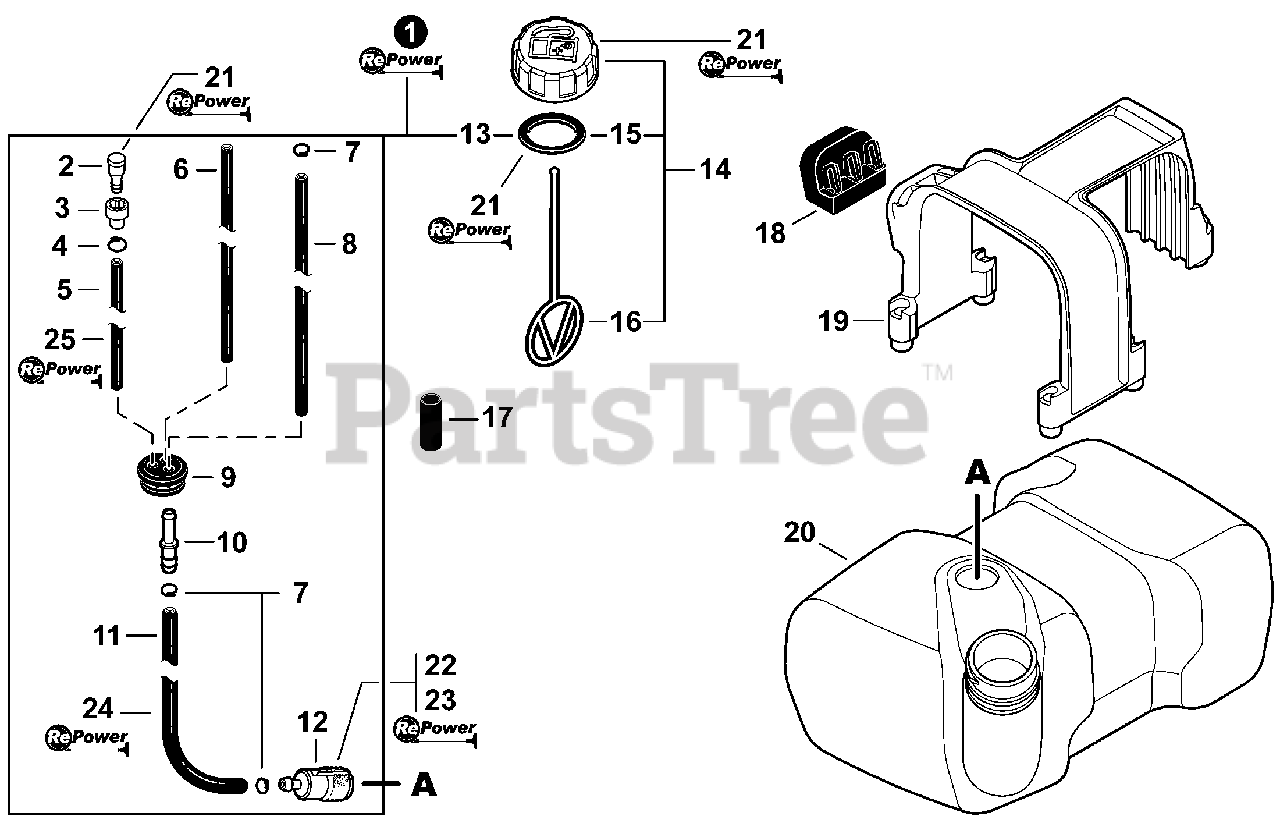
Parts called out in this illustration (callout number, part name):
1	FUEL SYSTEM KIT
2	VENT ASSY
3	HOLDER, VENT
4	CLIP Ø6.5 MM
5	PIPE, FUEL 3×6×130 BLACK
6	PIPE, FUEL 2.4×5×200 BLACK
7	CLIP Ø6
8	PIPE, FUEL 3×5×135L BLACK
9	GROMMET, FUEL
10	CONNECTOR, PIPE Ø5ר3.5
11	PIPE, FUEL 3×5×105L BLACK
12	FILTER, FUEL
13	GASKET, FUEL CAP
14	CAP ASSY, FUEL
15	GASKET, FUEL CAP
16	CONNECTOR, CAP L= 100 MM
17	TUBE, FUEL LINE 16×18×L40
18	CUSHION
19	RETAINER, FUEL TANK
20	TANK, FUEL
21	CAP/VENT KIT - REPOWER
22	TUNE-UP KIT - REPOWER
23	FILTER KIT - REPOWER
24	BULK PIPE - 3×5 MM BLACK (4 PIECES×2 M)
25	BULK PIPE - 3×6 MM BLACK (4 PIECES×2 M)
